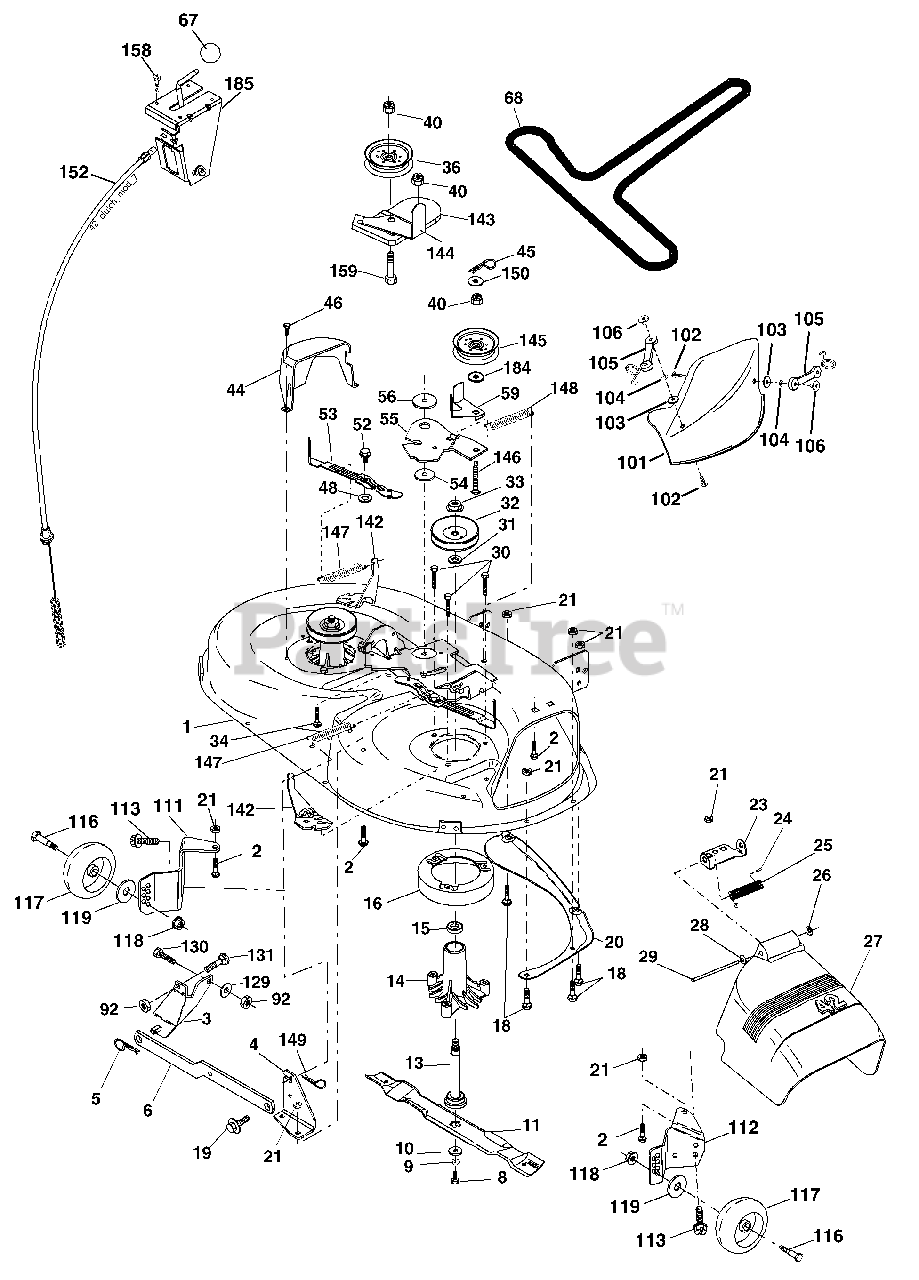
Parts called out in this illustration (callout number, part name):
1	Mower Deck Assembly, 42"
2	Bolt
3	Bracket Assembly,Sway Bar, Front
4	Bracket Sway Bar 38/42" Deck
5	Retainer Spring
6	Bar Sway Deck
8	Bolt, Hex 3/8-24 x 1.25 Gr. 8
9	Washer, Lock
10	Washer, Hardened
11	Blade, 42" Mulching Std
11	Blade, 42" Mulching Premium
11	Blade, 42" Hi-Lift
13	Shaft Assembly, Mandrel, Vented
14	Housing, Mandrel, Vented
15	Bearing, Ball, Mandrel
16	Stripper, Vented Mower Deck
18	Bolt, Carriage 5/16-18 x 5/8
19	Bolt, Shoulder
20	Baffle, Vortex
21	Nut Crownlock 5/16-18 Unc
23	Bracket, Deflector
24	Cap, Sleeve
25	Spring, Torsion, Deflector
26	Nut, Push
27	Shield, Deflector
28	Washer 11/32 x 5/8 x 16 Ga.
29	Rod, Hinge
30	Screw Thdrol Washer Head
31	Washer, Spacer
32	Pulley, Mandrel
33	Nut, Toplock, Flanged
34	Bolt Carr. Sh 3/8-16 x 1-1/2 Gr. 5
36	Pulley, Idler, Flat
40	Nut Crownlock 3/8-16 Unc
44	Guard, Mandrel, L.H.
45	Retainer
46	Screw, Thd. Roll 1/4-20 x 5/8
48	Washer, Hardened
52	Bolt, Shoulder 5/16-18 Unc
53	Arm Assembly, Pad, Brake
54	Washer, Hardened
55	Arm, Idler
56	Spacer, Retainer
59	Guard, TUV Idler
67	Knob
68	V-Belt
92	Nut
101	Mulcher Cover
102	Screw
103	Washer #10
104	Washer, Lock
105	Latch Assembly, Bagger
106	Nut, Weld
111	Bracket Gauge Wheel Lh
112	Bracket Gauge Wheel Rh
113	Screw 5/16-18 Unc
116	Bolt Shoulder
117	Wheel Gauge Std
118	Nut Centerlock 3/8-16 Unc
119	Washer 3/8 x 7/8 x 4 Ga.
129	Washer 13/32 x 13/16 x 12 Ga.
130	Bolt, Fin Hex 3/8-16 Unc x 1 Gr. 5
131	Bolt, Rdhd Sqnk 3/8-16 Unc x1
142	Arm Spring Brake Mower
143	Bracket Arm Idler 42"
144	Keeper Belt 42" Clutch Cable
145	Pulley Idler Flat
146	Bolt Carriage Idler
147	Spring Extension
148	Spring Return Idler
149	Retainer Spring Yellow Zinc
150	Washer 9/32 x 3/4 x 10 Ga.
152	Cable Clutch 42 In
158	Screw Hex Thd Cut 1/4-20 x 1/2
159	Bolt Rdhd Sqn 3/8-16 Unc x 3/4
184	Washer 13/32 x 7/8 x 10 Ga.
185	Head Asm. Cable Clutch
